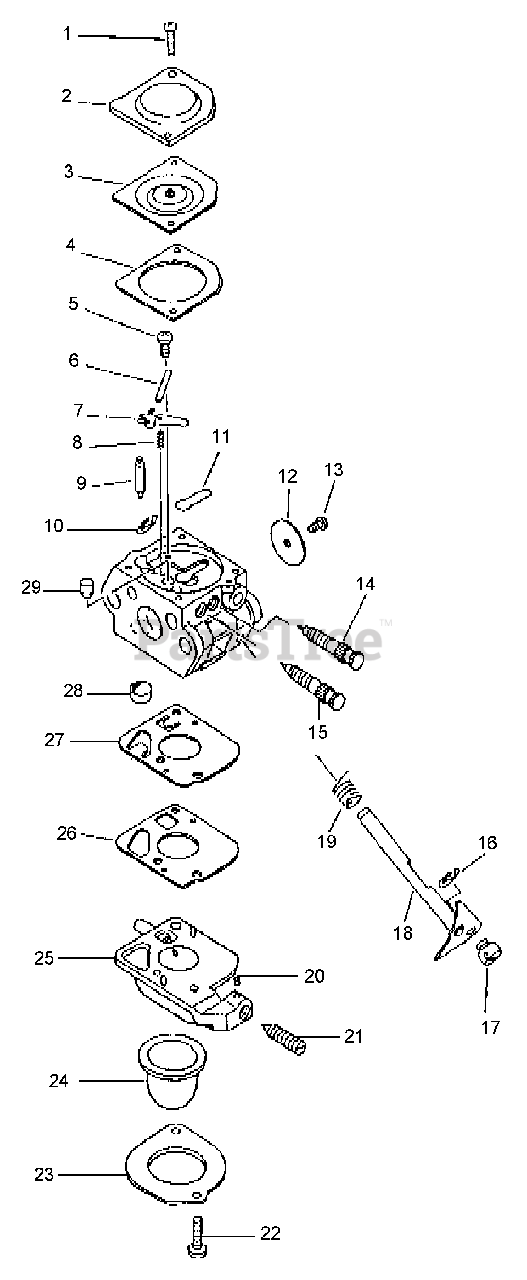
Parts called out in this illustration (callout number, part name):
1	SCREW
2	COVER, METERING DIAPHRAGM
3	DIAPHRAGM, METERING
4	GASKET, METERING
5	SCREW
6	PIN, METERING LEVER
7	LEVER, METERING
8	SPRING, METERING LEVER
9	VALVE, NEEDLE
10	E-RING
11	PLUG, WELCH
12	VALVE, THROTTLE
13	SCREW
14	NEEDLE, LOW SPEED
15	NEEDLE, HIGH SPEED
16	CLIP
17	SWIVEL
18	SHAFT, THROTTLE
19	SPRING, THROTTLE RETURN
20	PIECE, FRICTION
21	SCREW, IDLE ADJUST
22	SCREW
23	RETAINER
24	BULB, PURGE
25	BODY ASSY, PURGE
26	GASKET, PUMP
27	DIAPHRAGM, PUMP
28	STRAINER
29	NOZZLE, CHECK VALVE
